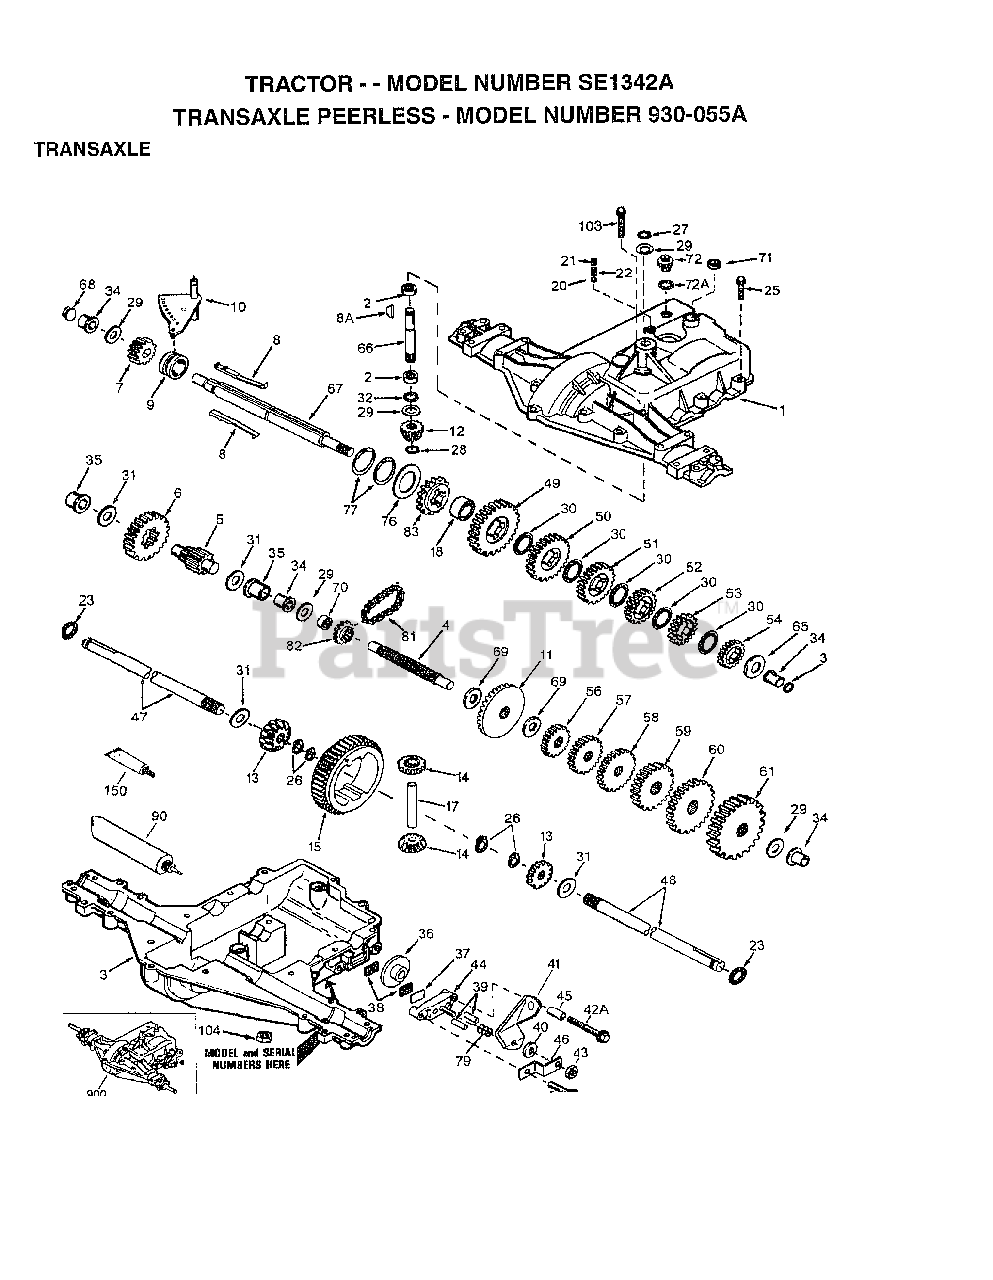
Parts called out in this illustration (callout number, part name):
1	TRANSAXLE COVER
2	BEARING, NEEDLE
3	TRANSAXLE CASE
4	SHAFT, COUNTER
5	OUTPUT SHAFT AND PINION
6	GEAR, OUTPUT
7	GEAR, SPUR, 15 TEETH
8A	KEY, WOODRUFF
9	COLLAR, SHIFTER
10	ROD & FORK ASSY, SHIFT
11	GEAR, BEVEL, 42 TEETH
12	BEVEL PINION, INPUT
13	GEAR, BEVEL
14	GEAR, BEVEL, PINION
18	SPACER, NEUTRAL
20	BALL STEEL, 5/16" DIA.
21	SCREW, 3/8-16 X 3/8"
25	SCREW, 1/4-20 X 1-1/4
26	RING RETAINER
27	RING, RETAINER
28	RETAINING RING
29	WASHER THRUST
30	WASHER THRUST
33	SEAL, SQUARE CUT
34	BUSHING, FLANGED
35	BUSHING, FLANGED
36	DISK, BRAKE
37	PLATE BRAKE PAD
41	BRAKE LEVER
42	SCREW, 1/4-20 X 1-1/4
42A	SCREW, 1/4-20 X 2-1/4
44	HOLDER BRAKE PAD
49	GEAR, SPUR, 37 TEETH
50	GEAR, SPUR, 35 TEETH
51	GEAR, SPUR, 30 TEETH
52	GEAR, SPUR, 25 TEETH
53	GEAR, SPUR, 22 TEETH
54	GEAR, SPUR, 19T
56	GEAR, SPUR, 12 TEETH
57	GEAR, SPUR, 15 TEETH
58	GEAR, SPUR, 20 TEETH
59	GEAR, SPUR, 25 TEETH
60	GEAR, SPUR, 28 TEETH
61	GEAR, SPUR, 31 TEETH
65	WASHER, THRUST
66	SHAFT, INPUT
67	SHAFT, BRAKE, 4 KEYED
69	WASHER THRUST
71	SEAL SQUARE CUT
72	THREADED PLUG 9/16-18
76	WASHER, THRUST
77	INVERTED RETAINING RING
81	CHAIN, ROLLER
82	SPROCKET 9T
83	SPROCKET 18T (REV)
90	GREASE BENTONITE, 32 OZ.
150	GASKET ELIMINATOR
432	LOCKNUT 5/16-24
465	BRKT BRAKE LEVER
900	REPLACEMENT TRANSAXLE
